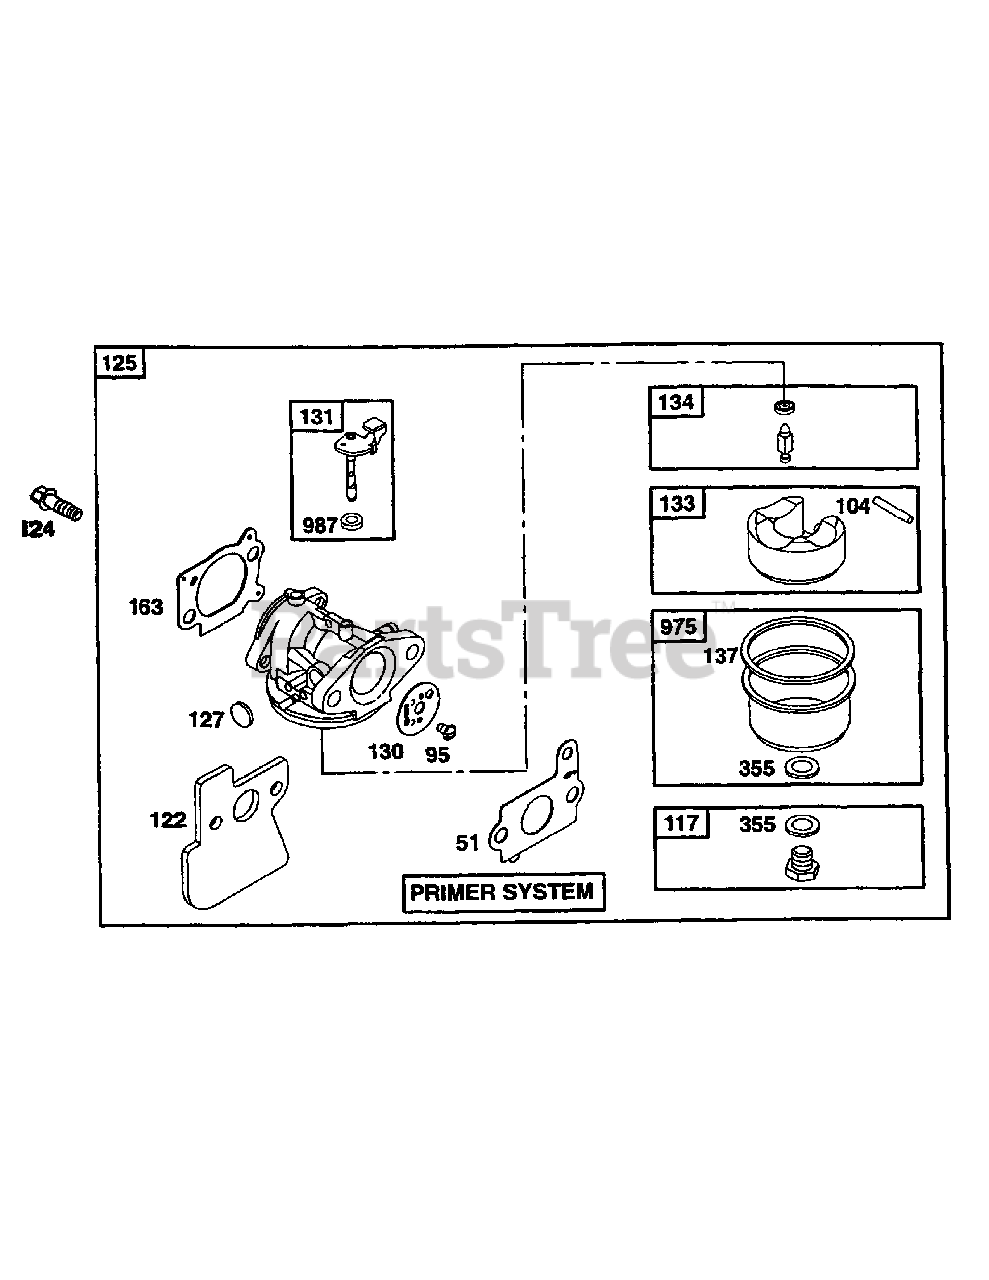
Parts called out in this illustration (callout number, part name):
51	Intake Gasket
95	Round Head Screw
104	Float Pin
117	Main Jet
122	Carburetor Spacer
124	Screw Hex
125	Carburetor
127	Welch Plug
130	Throttle Valve
131	Throttle Shaft
134	Needle Valve
137	Float Bowl Gasket
163	Air Cleaner Gasket
355	Seal Washer
975	Float Bowl
987	Throttle Shaft Seal
